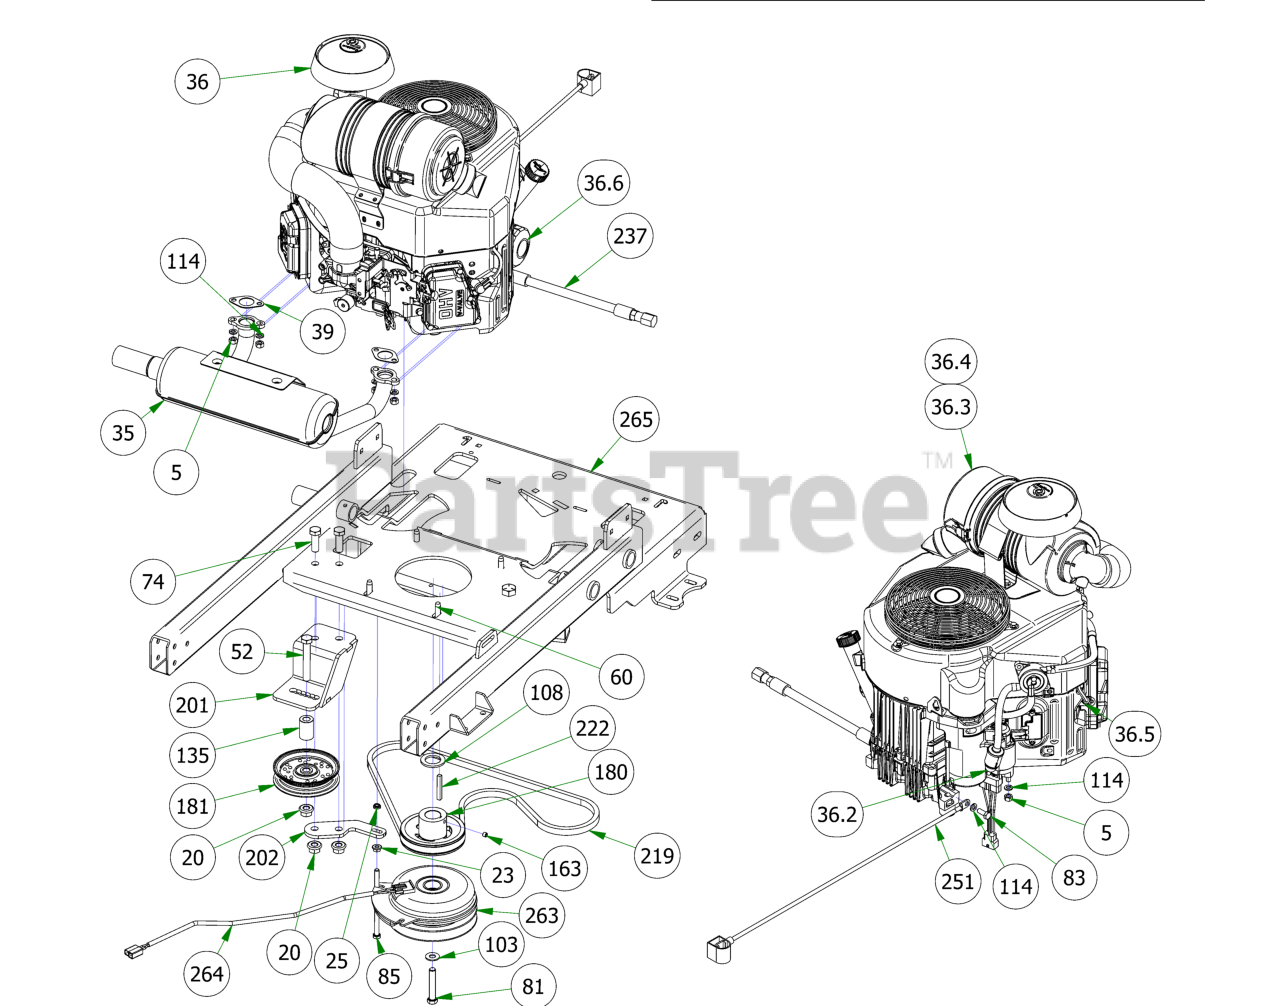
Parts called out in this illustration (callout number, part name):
5	M8-1.25 DIN 934 HEX NUT (CL.8) ZINC
20	1/2-13 NYLON INSERT FLANGE LOCKNUT ZINC
23	5/16-18 HEX SERRATED FLANGE NUT HARD/ZINC
25	5/16-18 NYLON INSERT JAM LOCKNUT ZINC
35	Exhaust-Stand On-FX691V Kawasaki
36	FX-730 Kawasaki
36.1	Exhaust Gasket
36.2	Universal Inline Fuel Filter
36.3	Canister Air Filter- Outer
36.4	Canister Air Filter- Inner
36.5	Spark Plug - Kawasaki
36.6	Oil Filter
39	Exhaust Gasket
52	1/2-13 X 3-1/4 HEX CAP SCREW (GR.5) ZINC
60	3/8-16 X 1-1/8HEX WASHER UNSLOT SERRATED (TRI-LOB) TRS
74	1/2-13 X 1-1/2 HEX CAP SCREW (GR.5) ZINC
81	7/16-20 X 2-1/2 HEX CAP SCREW (GR.8) ZINC YELLOW
83	M8-1.25 X 20MM DIN 933 HEX TAP BOLT (CL 8.8) ZINC
85	5/16-18 X 5-1/2 HEX CAP SCREW (GR.5) ZINC
103	3/8 FLAT WASHER USS (1" OD) ZINC
108	1.140 ID X 1.750 OD X .132 THICK FLAT WASHER PLAIN
114	5/16 SPLIT LOCKWASHER ZINC
135	.502 ID X .750 OD X 1.500 Long Spacer
163	5/16-24 X 1/4 SOCKET SET SCREW (CUP PT) PLAIN
180	4 3/4 Motor Pulley
181	4 3/4 Idler Pulley - ABFI-76
201	Idler Pulley Bracket Weldment 2019 Stand On
202	2019 Stand On Clutch Stop Bracket
219	2019 Stand On Pump Belt (Timken# 47-2827)
222	1/4 X 2 SQ MACHINERY KEY 1018 STL PLAIN
237	Kawasaki Oil Drain
251	24 inch Black Cable – MZ/ZT
263	Clutch Assembly
264	Clutch Pigtail
265	2019 Stand On Frame
292	2019 Harness Adaptor-Gen2 FX-ALL
